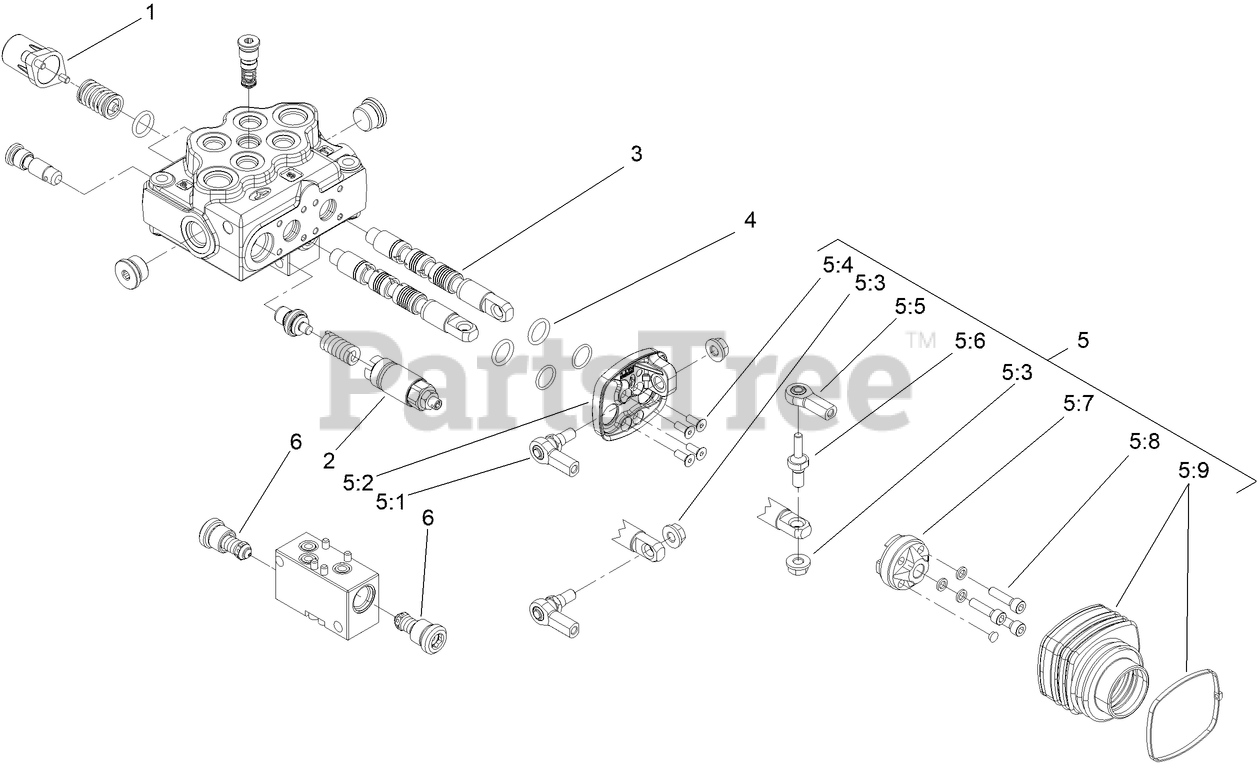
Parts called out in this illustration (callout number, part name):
1	HIGH FORCE SPRING KIT
2	VALVE-RELIEF
3	VALVE-SPOOL
4	SEAL-VALVE
5	JOYSTICK KIT
5:1	JOINT-JOYSTICK
5:2	BASE-JOYSTICK
5:3	NUT-HF, LOCK
5:4	SCREW-JOYSTICK
5:5	JOINT-JOYSTICK
5:6	PIN-SPOOL
5:7	HOLDER-JOYSTICK
5:8	SCREW-HSH
5:9	BOOT-JOYSTICK
6	VALVE KIT
